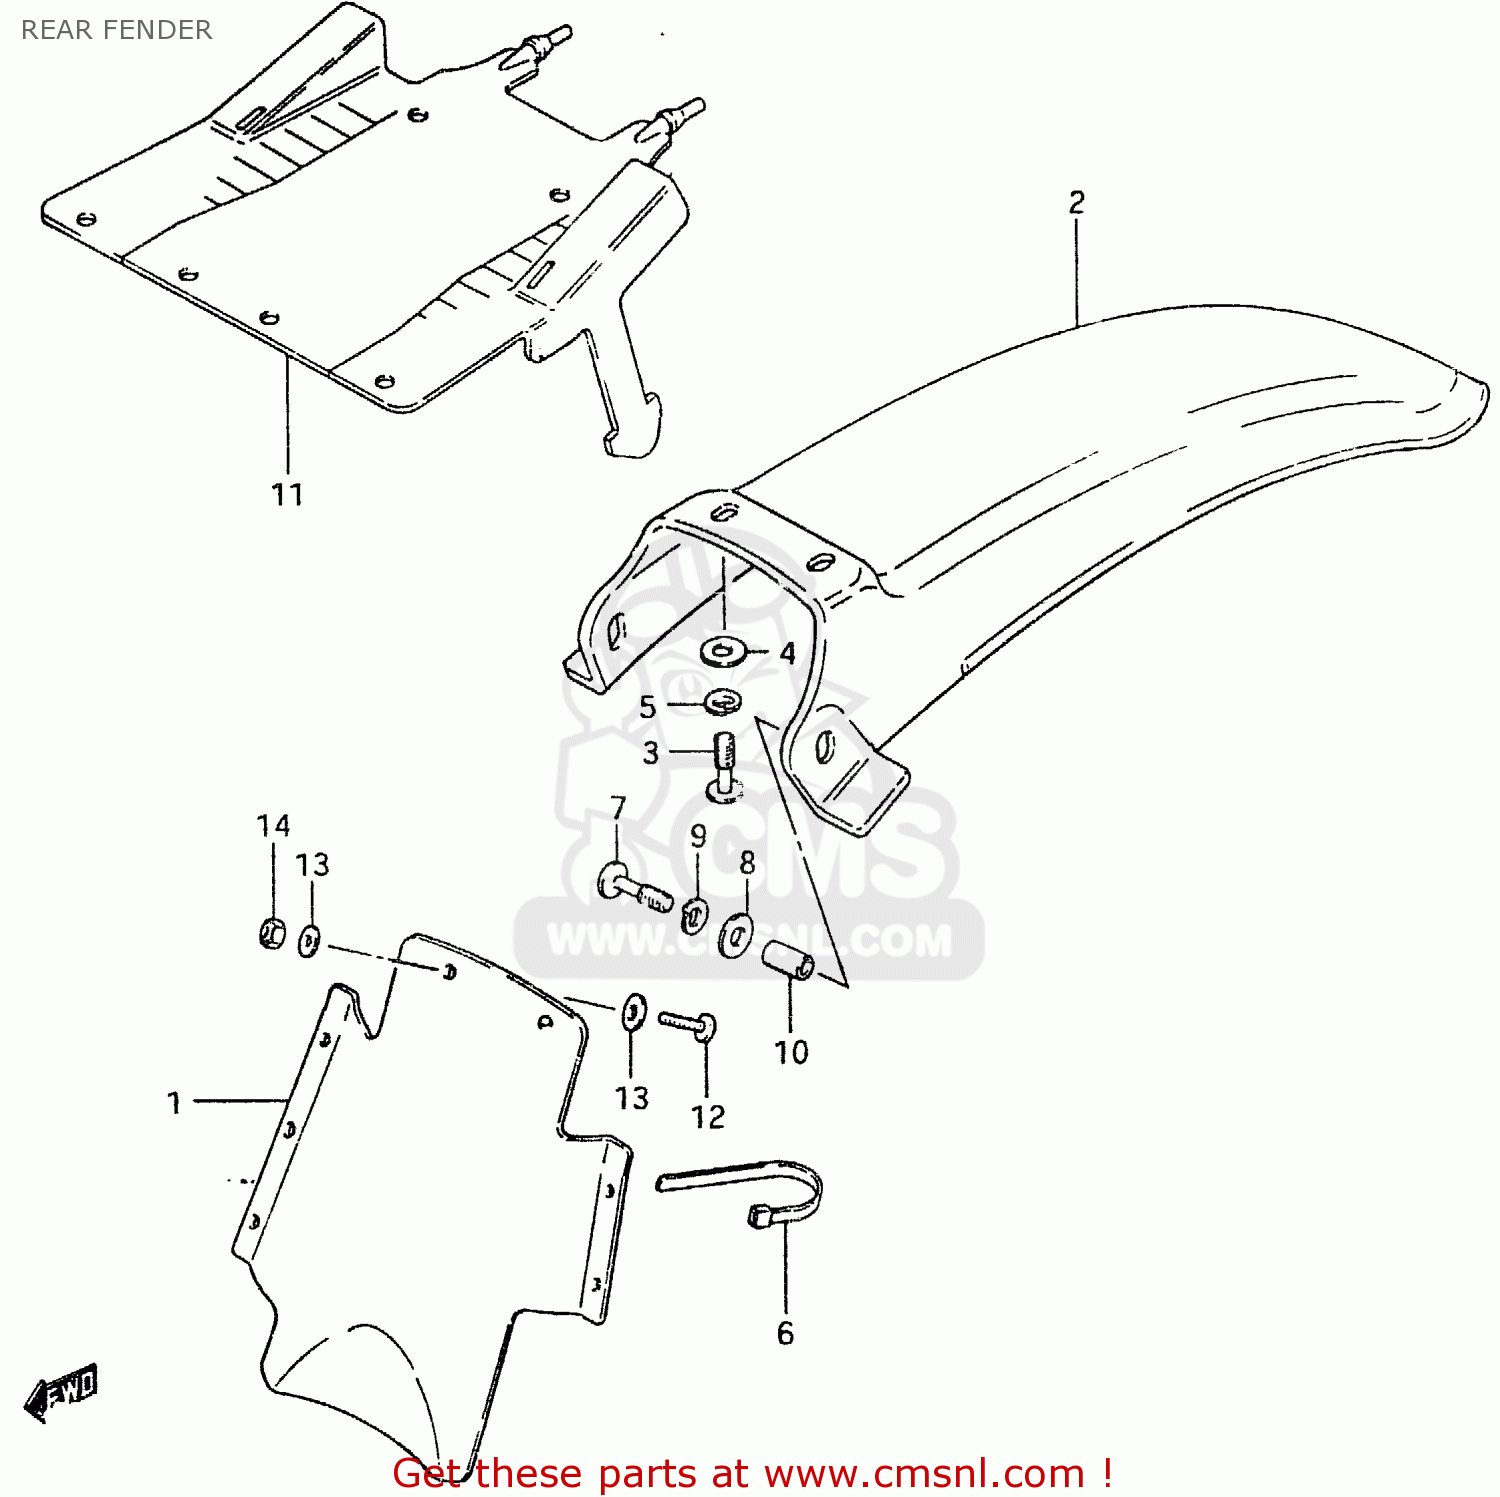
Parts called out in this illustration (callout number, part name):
1	FENDER,REAR
2	FENDER,REAR
3	SCREW
4	WASHER (6.5X20X1.2)
5	LOCK WASHER
6	CLAMP
7	SCREW
8	WASHER (6.5X20X1.2)
9	LOCK WASHER
10	SPACER
11	GUIDE,RR FENDER MUD
12	SCREW
13	WASHER
14	NUT
